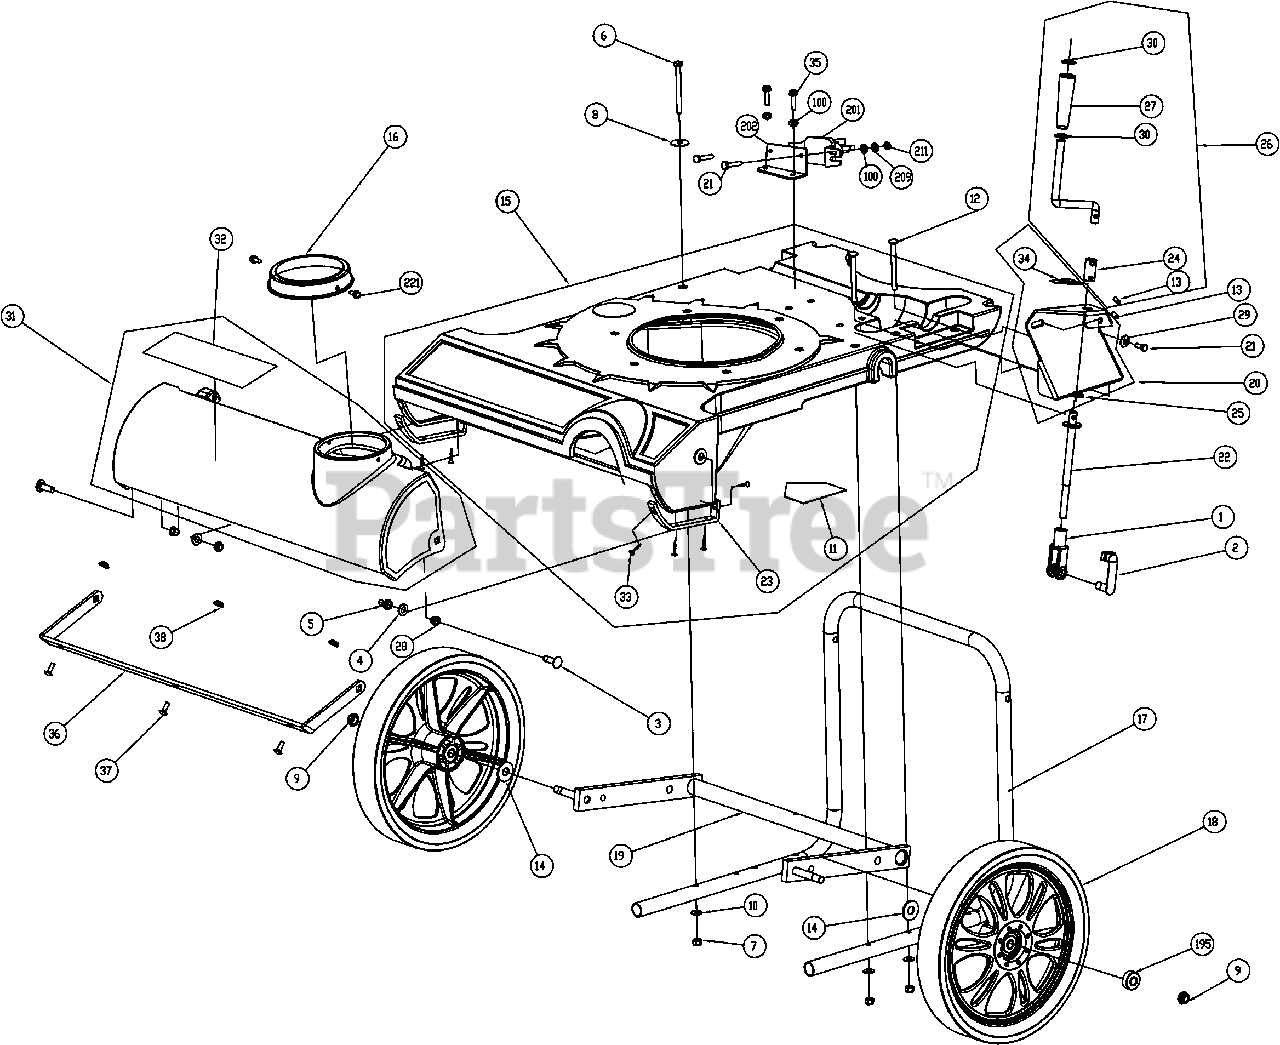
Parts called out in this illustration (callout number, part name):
1	YOKE 1/2 - 20
2	PIN YOKE 1/2"
3	SCREWCAP BUTTON HEAD 3/8"-16 X 1 1/4" PL
4	WASHER 3/8" SAE ZP
5	NUT LOCK 3/8-16 LT WT THIN ZP
6	SCREWCAP 5/16 -18 x 3 1/2
7	NYLON INSERT LOCKNUT 5/16-18 UNC
8	WASHER FLAT FENDER 5/16
9	NYLON INSERT LOCKNUT 1/2-13 UNC THIN
10	WASHER 1/4" FC ZP
11	LABEL WARNING OPEI
12	BOLTCARRIAGE 5\16-18X3 1\2
13	ROLL PIN 1/4 X 1 LONG
14	WASHER 1/2" SAE ZP
15	NOZZLE MV VAC ASSEMBLY
16	CAP 5 IN HOSE VAC
17	HANDLE LOWER MV VAC
18	WHEEL 14" ASSEMBLY WITH BEARING AND TIRE
19	AXLE FRONT WA MV VAC
20	BRACKET HGT ADJ WA W/LABEL MV VAC
21	SCREWCAP 1/4 - 20 x 0.75 HWH
22	LINK HGT ADJ MV VAC
23	BRACKET NOZZLE WEAR GUARD MV VAC
24	ROD CONNECT HGT ADJ
25	BUSHING 0.5" ID 0.625 OD X X 0.250
26	ROD HANDLE CRANK ASSEMBLY
27	HANDLE CRANK 0.5 ID X 3.72 LONG
28	BUSHING 3/8" ID 1/2" OD X 3/8" LONG
29	WASHER LOCK 1/4" TWISTED TOOTH
30	NUT PAL 0.5" ID x 0.75 OD
31	NOZZLE COVER MV VAC
32	LABEL MV BADGING
33	SCREW PLASTIC 5/8
34	LABEL HGT ADJ MV VAC
35	SCREW SELF-TAP 5/16 NC X 3/4 HEX
36	BRACKET NOZZLE COVER REINFORMENT MV
37	BOLT CARRIAGE 1/4-20X0.75
38	NUT FLANGE 1/4-20
100	WASHER 1/4" SAE ZP
195	MV WHEEL BEARING
201	SOLENOID ELEC START
202	BRACKET SOLENOID MOUNT MV
209	WASHER LOCK 1/4" EXT TOOTH
211	NUT 1/4" FIN HEX ZP
221	SCREW PLASTITE 1/4"-10 X 3/4"
